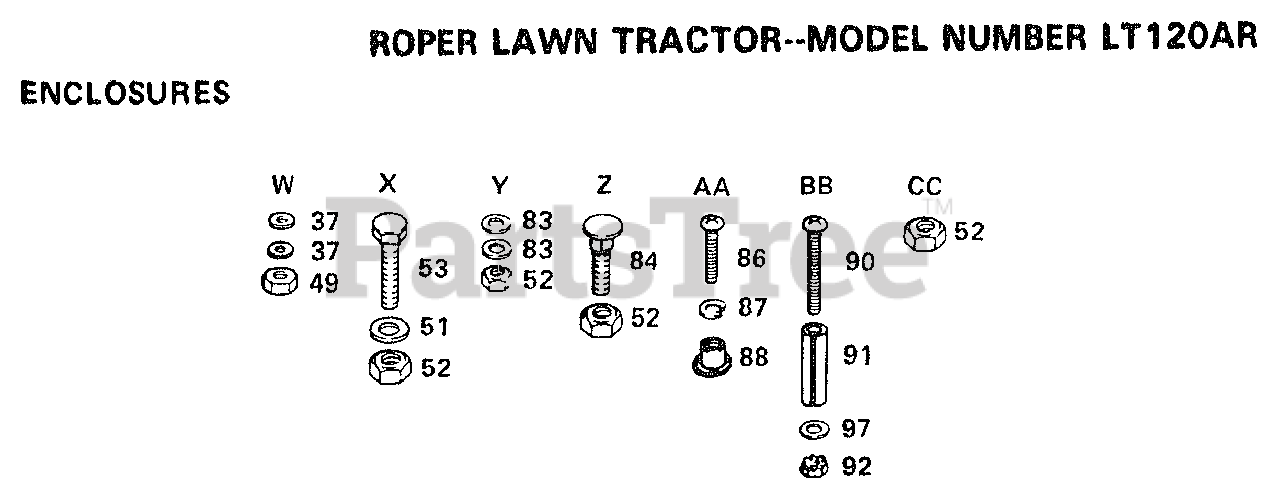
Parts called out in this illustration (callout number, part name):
37	WASHER PM
51	WASHER
53	BOLT
83	WASHER
84	BOLT
86	SCREW
87	LOCKWASHER
88	WELDNUT
90	SCREW
91	SPACER LT
97	WASHER
